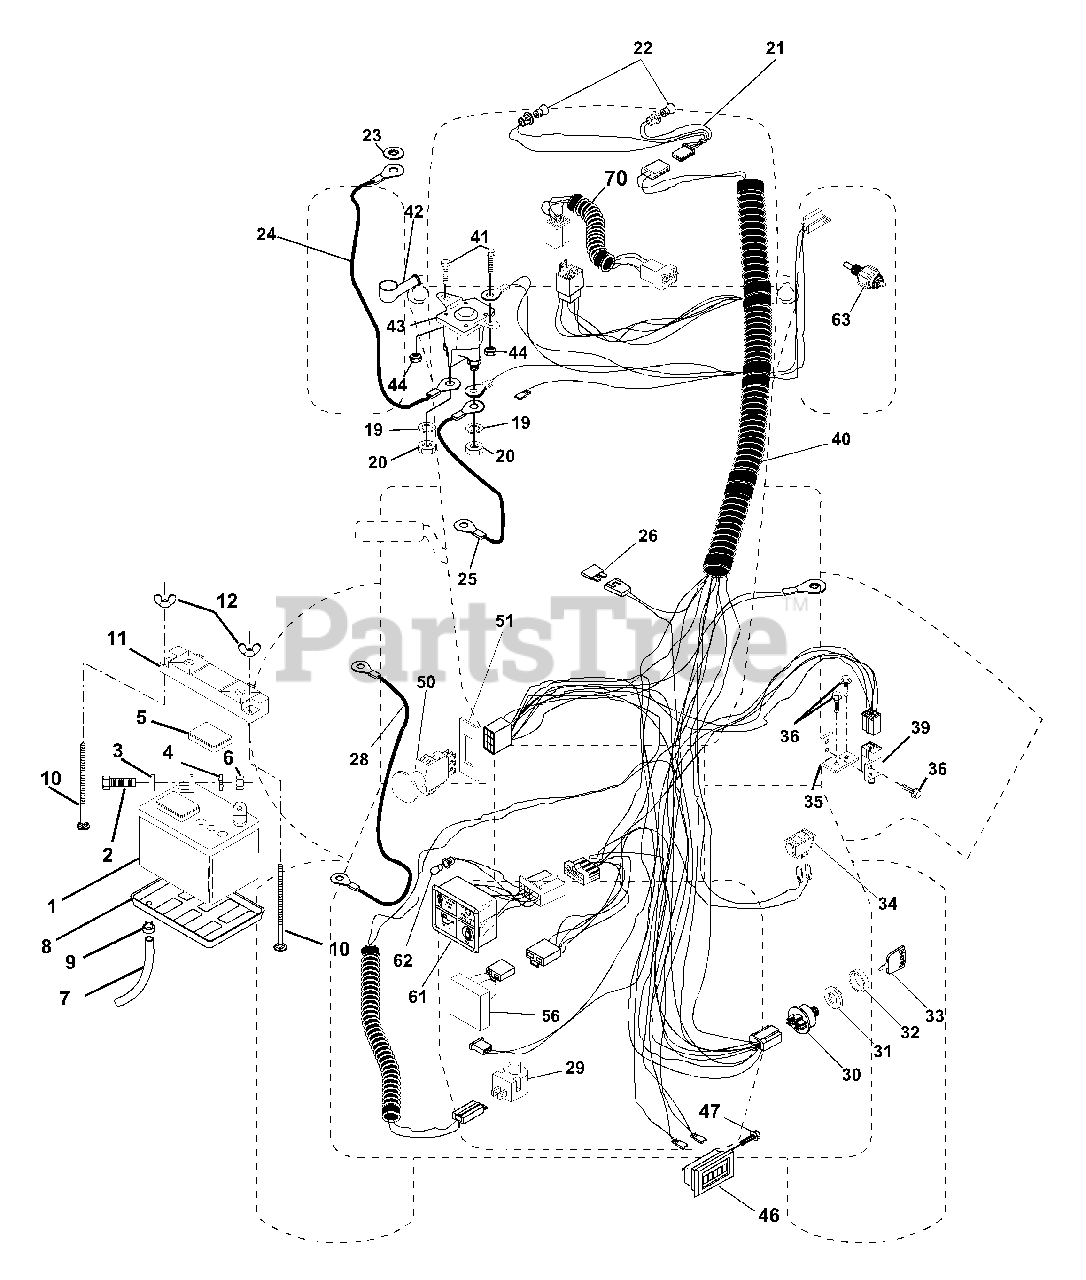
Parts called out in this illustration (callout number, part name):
1	Battery
2	Bolt, Hex Head 1/4-20 x 3/4
3	Washer 9/32 x 5/8 x 16 Gauge
4	Washer, Lock 1/4
5	Caps, Battery
6	Nut, Hex 1/4-20
7	Tube, Tray, Battery
8	Tray, Battery
9	Clamp, Hose
10	Bolt, Carriage 1/4-20 x 7-1/2
11	Guard, Terminal
12	Nut, Wing 1/4-20
19	Washer, Lock 1/4
20	Nut, Hex, Jam 1/4-20
21	Harness, Socket, Light
22	Bulb, Light
23	Washer, Lock, Internal Tooth 1/4
24	Cable, Battery (2)
25	Cable Starter 6 Ga. 11" Red
28	Cable, Battery
29	Switch, Plunger
30	Switch, Ignition
31	Nut, Ignition
32	Bezel, Ignition
33	Key, Molded
34	Switch, Light
35	Bracket Switch Interlock
36	Screw, Hex Tap #10-24 UNC
39	Switch, Intlk 4 Term
40	Harness, Ignition
41	Bolt, Hex1/4-20 x 1/2 Grade 5
42	Cover, Terminal
43	Solenoid
44	Nut, Hex, Keps 1/4-20
46	Meter, Hour
47	Screw #10-24 x 1/2
50	Switch, P.T.O.
51	Ring, Retainer PTO
56	Sensor, Low Voltage
61	Package, Light
62	Bulb Dashboard Light 27 amp.
63	Wire Lead Sentry Kohler
70	Harness Eng. Koh. Tw 16 AR O Pump
